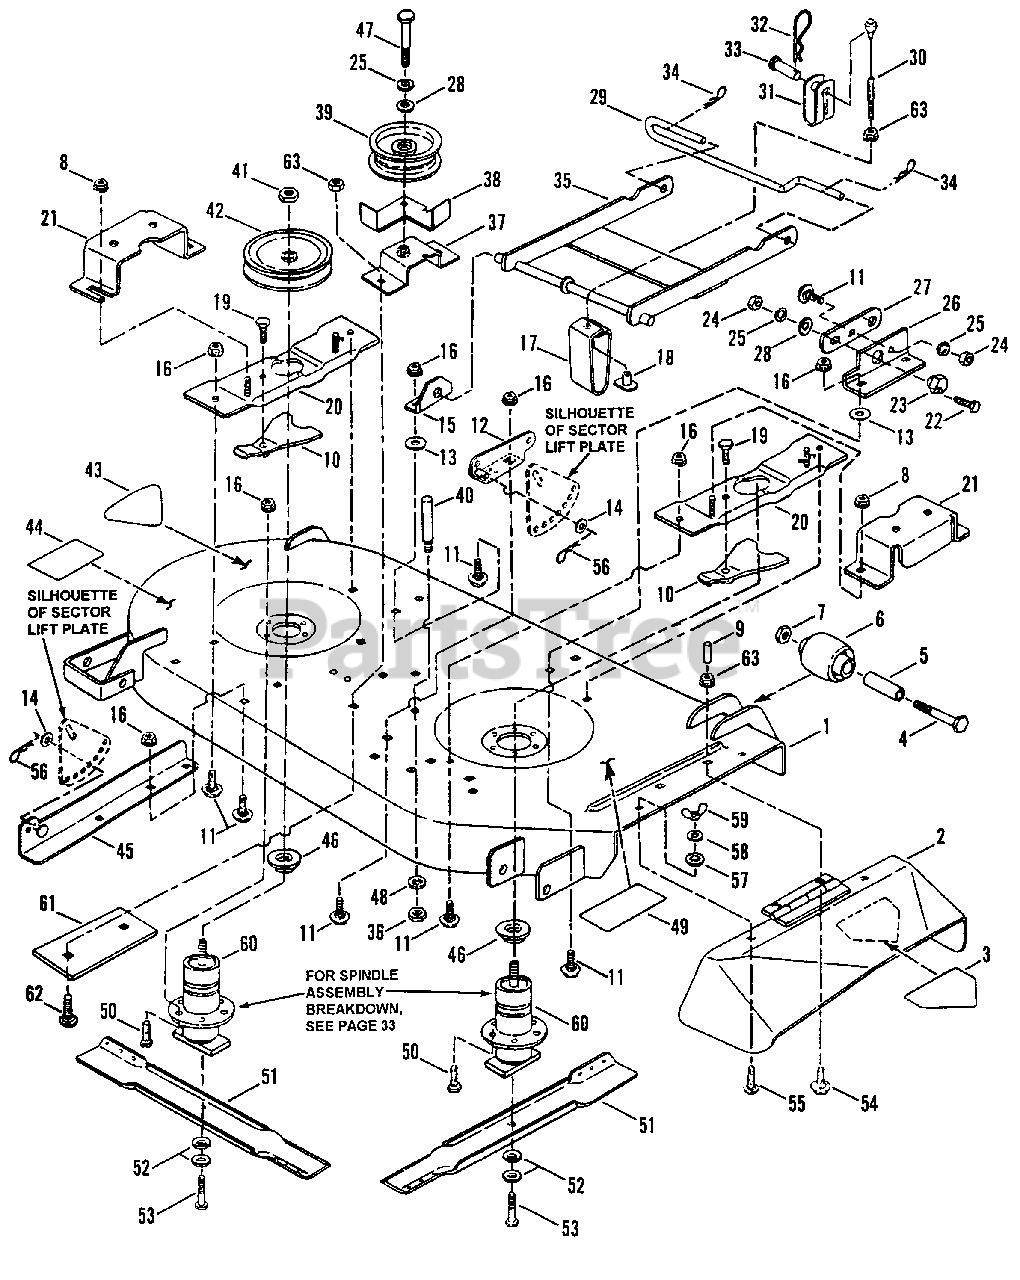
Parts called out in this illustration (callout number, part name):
1	ASSEMBLY, Deck, 42" Cutting
2	DEFLECTOR, Side Discharge
3	DECAL - DANGER
4	SCREW, 3/8-24 x 3 3/4" Hex Head Cap
5	SPACER
6	WHEEL, Gage
7	NUT, 3/8-24 Hex Center Lock, Grade 5
8	NUT, 5/16-18 Hex Flange Lock
9	CAP, Vinyl
10	ASSEMBLY, Spindle Lock
11	BOLT, 3/8-16 x 3/4" Carriage
12	BRACKET, Lift (Right Side)
13	WASHER, Flat
14	WASHER, 3/8" Flat
15	BRACKET, Front Hanger (Left Side)
16	NUT, 3/8-16 Hex Flange Lock
17	BRACKET, Front Lift Arm Hanger
18	T-NUT, 5/16-18
19	BOLT, 3/8-16 x 1" Hex Flange Lock
20	ASSEMBLY, Spindle Brace
21	GUARD, Pulley
22	SCREW, 3/8-16 x 1" Hex Head Cap
23	ECCENTRIC, Leveling
24	NUT, 3/8-16 Hex
25	WASHER, 3/8 Split Lock
26	BRACKET, Front (Right Side)
27	LINK, Adjustment
28	WASHER, 3/8" Flat
29	PIN, Deck Hanger
30	CABLE, Deck Lift
31	CLEVIS, Lift Cable
32	PIN, Hair, 3/32 x 1-1/2"
33	PIN, Clevis, 3/8 x 1-1/16"
34	PIN, Hair, 148 x 2.62"
35	ASSEMBLY, Front Hanger
36	NUT, 3/8-24 Hex
37	BRACKET, Idler
38	GUIDE, Belt
39	PULLEY, Idler
40	STUD, Idler
41	NUT, 3/4-16 Hex Jam
42	PULLEY, Spindle
43	DECAL, 42" Deck
44	DECAL - CAUTION (Rotating Blades)
45	BRACKET, Deck Lift (Left Side)
46	WASHER, Spindle
47	BOLT, 3/8-24 x 2" Hex Head Cap, Grade 5
48	WASHER, 3/8 Internal Tooth Lock
49	DECAL - CAUTION
50	BOLT, 3/8-16 x 3/4" Hex Flange
51	BLADE, 21" Cutter
52	WASHER, Cone, 13/32 x 1 13/32" Diameter
53	SCREW, 3/8-24 x 1 1/4" Hex Head Cap, Grade 5
54	BOLT, 5/16-18 x 1" Short Neck Carriage, Grade 5
55	BOLT, 5/16-18 x 5/8" Carriage
56	PIN, Hair, .093 x 1.50"
57	RETAINER, 5/16 Bolt
58	WASHER, 5/16 Split Lock
59	WING-NUT, 5/16-18
60	ASSEMBLY, Spindle
61	PLATE, Support
62	SCREW, 5/16-18 x 1" Hex Head Cap,
63	NUT, 5/16-18 Hex Flange Lock Grade 5
